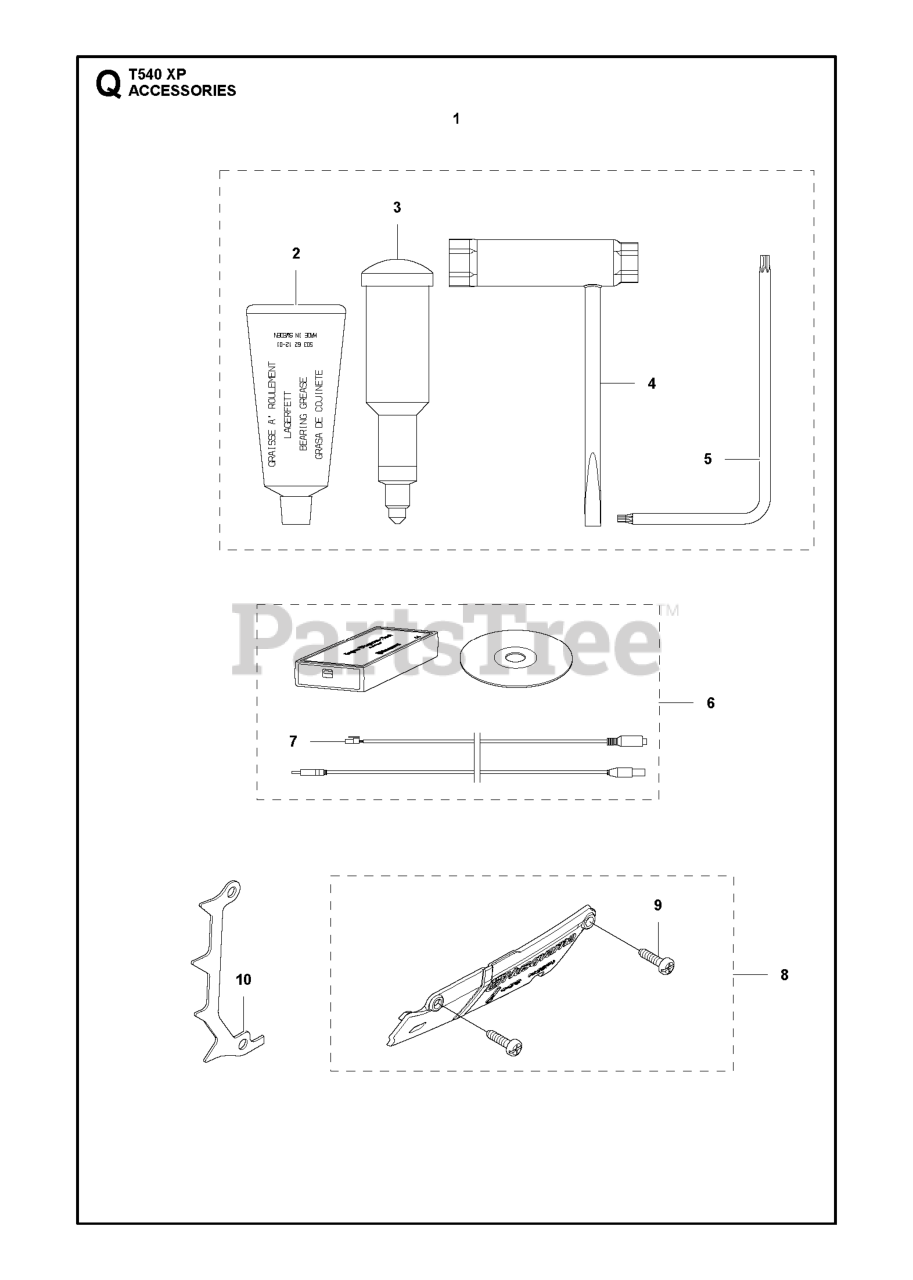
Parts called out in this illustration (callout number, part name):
2	GREASE
3	Grease Gun
4	COMBINATION WRENCH
6	SERVICE TOOLS
7	CABLE ASSY
8	WINTER KIT
